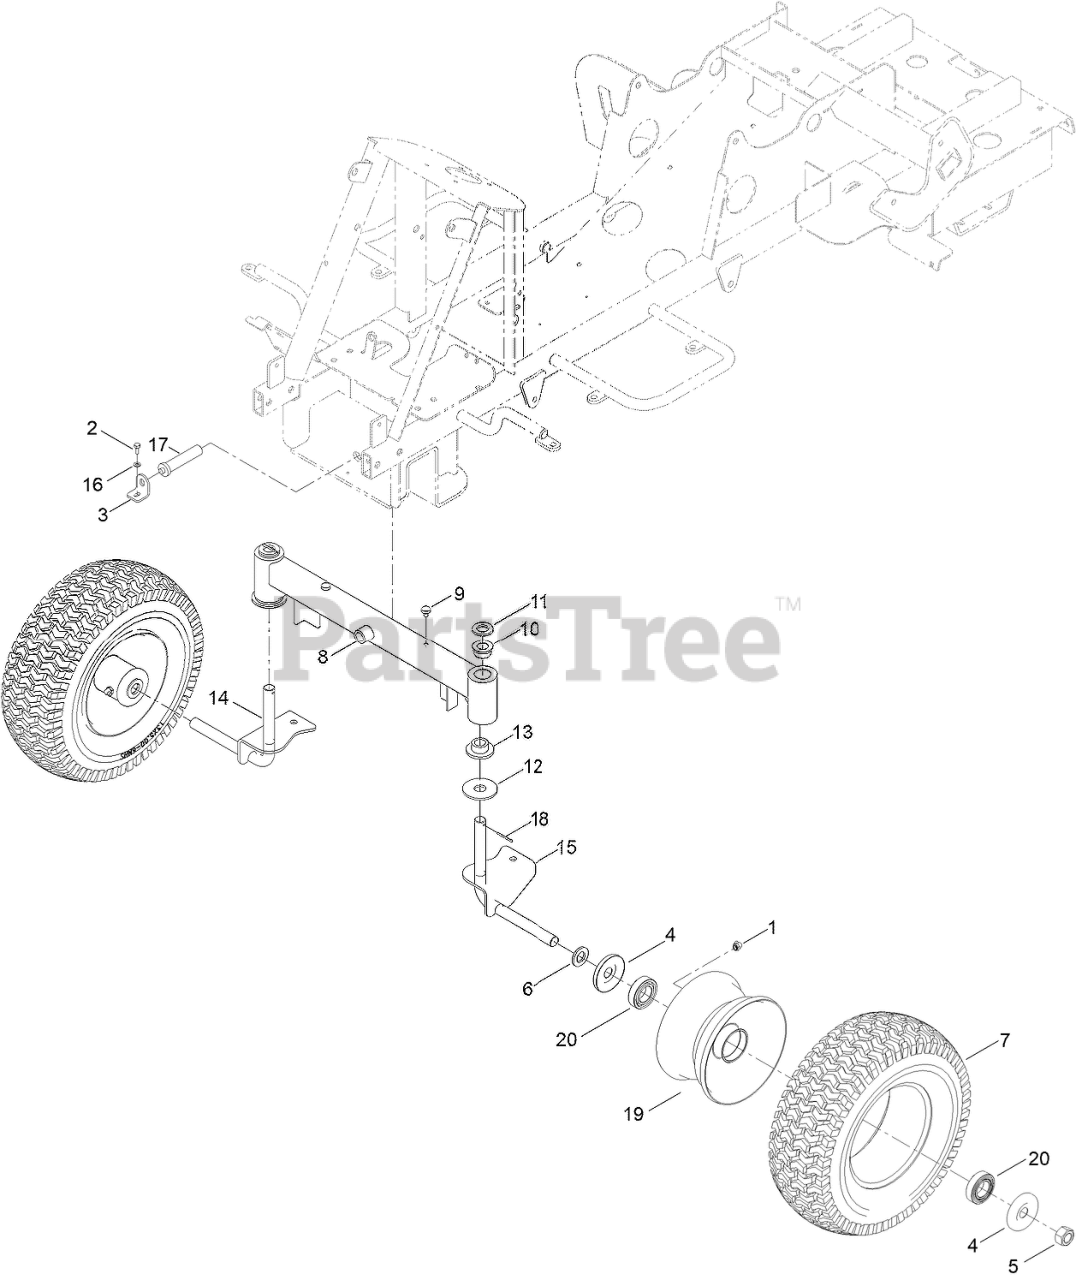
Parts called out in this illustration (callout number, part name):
1	GREASE NIPPLE 90
3	BRACKET, FRONT AXLE PIN
4	COVER, WHEEL BEARING
5	NUT, FRONT WHEEL
6	WASHER (WHEEL)
7	TYRE, WHEEL
8	FRONT AXLE ASM
9	STOPPER, FRONT AXLE TILT
10	SMALL BUSH, AXLE
11	WASHER
12	WASHER
13	LARGE BUSH, AXLE
14	MOUNT, WHEEL (LH)
15	MOUNT, WHEEL (RH)
16	WASHER
17	PIN, FRONT AXLE TILT
19	HUB, WHEEL (FRONT)
20	BEARING, WHEEL (FRONT)
